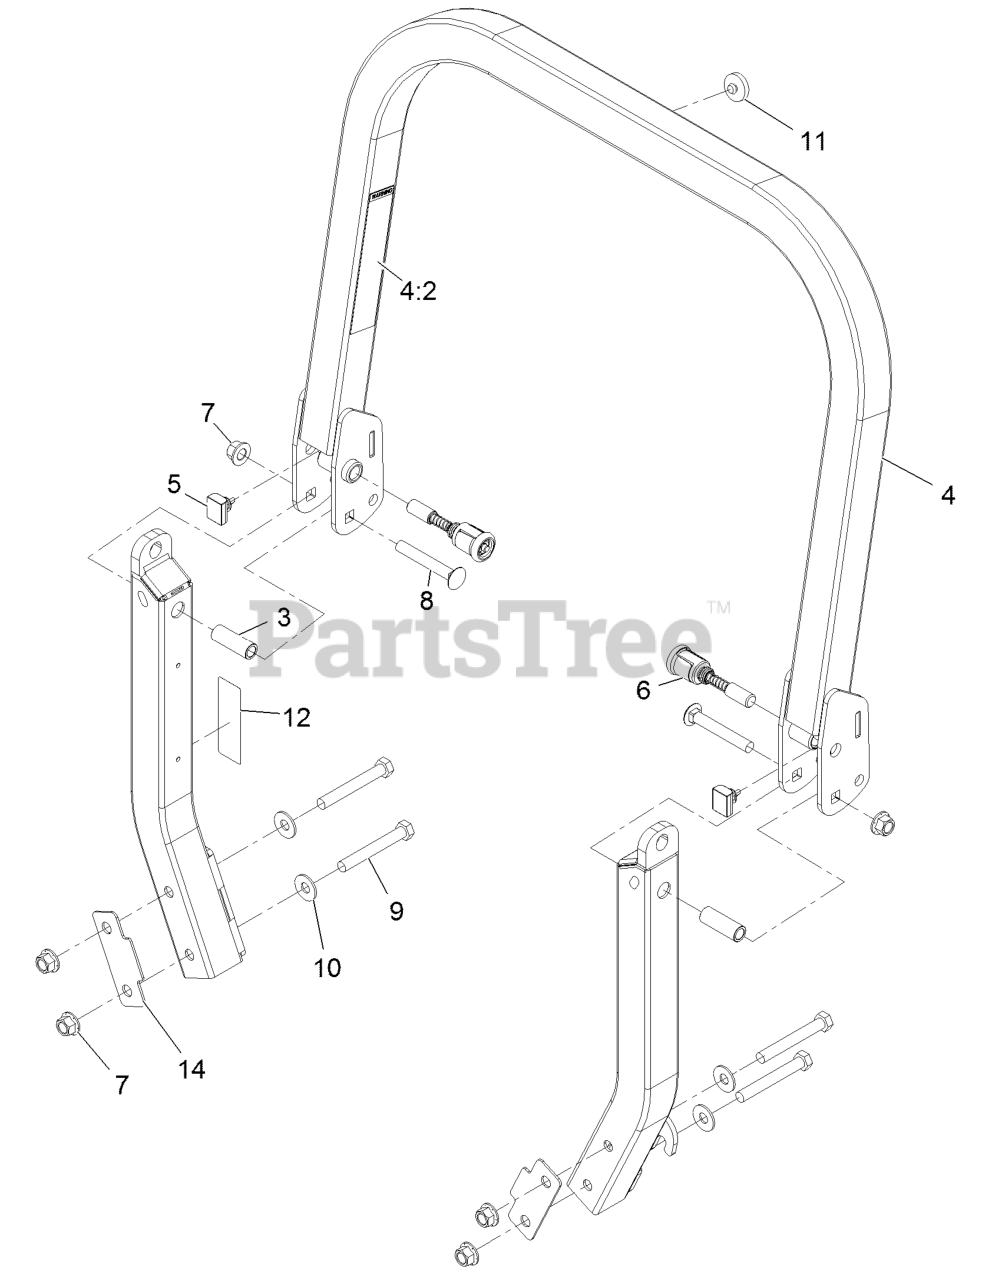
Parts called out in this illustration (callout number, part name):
4	UPPER ROPS ASM
4:2	DECAL-WARNING, FOLDING RO
5	BUMPER-ROPS
6	PIN-SPRING
7	Nut-Lock 1/2-13
8	SCREW-CARR
9	WASHER-LOCK
10	WASHER-SPRING
11	BUMPER-PUSH-IN, RUBBER
12	DECAL-CAUTION
